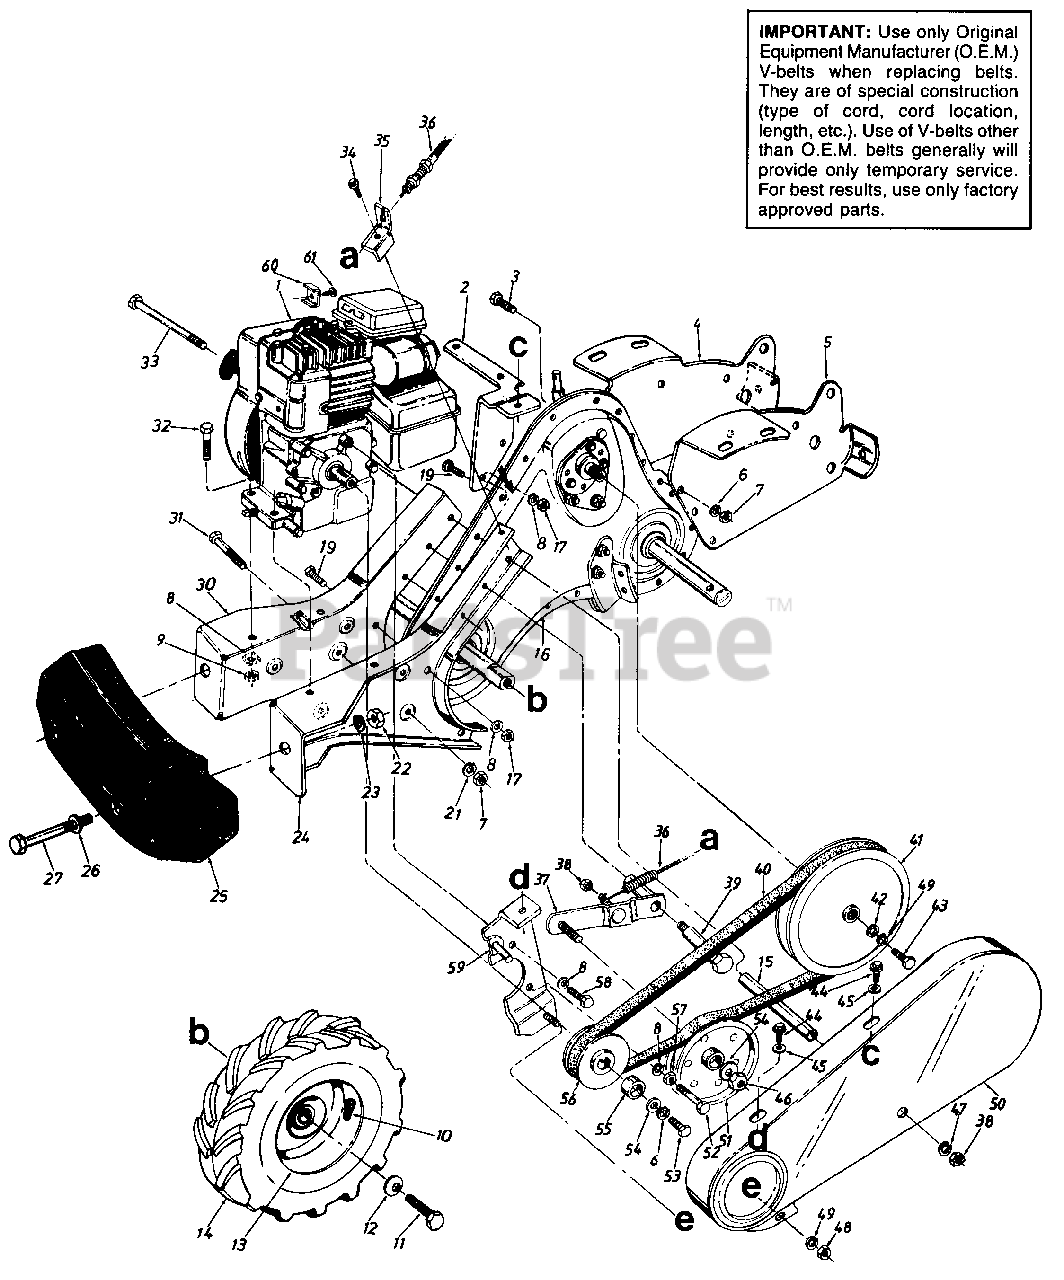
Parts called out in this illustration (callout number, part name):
1	Engine
7	Hex Nut 3/8-16 Thd .
8	L-Wash. 5/16" I.D.
9	Hex Nut 5/16-18n Thd.
10	Air Valve
11	Hex Bolt 5/16-24 x .62" Lg.
12	Bell-Wash. .345" I.D. x .88"
13	Wheel Rim Ass'y. Only
14	L.H. Wheel Ass'y. Comp.
16	Transmission Comp.
17	Hex Nut 5/16-18 Thd.
19	Hex Bolt 5/16-18 x .75" Lg.
21	L-Wash. 3/8" I.D.-H.D.
22	Hex Nut 1/2-13 Thd.
23	L-Wash. 1/2" I.D.
26	Fl-Wash. .510" I.D. x 1.0n
27	Hex Bolt 1/2-13 x 5 00n Lg.*
32	Hex Bolt 5/16-18 x 1.50
33	Hex Bolt 5/16-18 x 4 75n Lg.-Grade 2
34	Hex Wash. TT-Tap Scr. 5/16-1 8 x .62 Lg.
35	Bracket Clutch Cable
36	Clutch Control Cable 53n Lg.
39	Shld. Bolt .500n Dia. x 2.27n
40	"V"-Belt
41	"V"-Pulley Split 518" I.D.
42	Fl-Wash. 1/4" I.D. x .93n O.D.
43	Hex Bolt 1/4-28 x .75n Lg.
44	Hex Wash. Hd. S-Tap Scr. 1/4-20 x .50" Lg.
45	Fl-Wash. .281" I.D. x .625"
46	Hex Cent. L-Nut 3/8-24 Thd.
47	Fl-Wash. 6/16" I.D.
48	Hex Nut 1/4-20 Thd.
49	L-Wash. 1/4" I.D.
51	Fl-Idler w/Flanges 3.75" O.D.
52	Hex Bolt 5/16-24 x 1.75
53	Hex Bolt 3/8-24 x 1.00n Lg.
54	Fl-Wash. 818" I.D. x 1.00n
55	Spacer .758" I.D. x .ggon
56	Engine Pulley
57	Hex Nut 5/16-24 Thd.
58	Hex Bolt 5/16-24 x .62n Lg.
61	Hex Sems Scr. #10-32 x .62n
